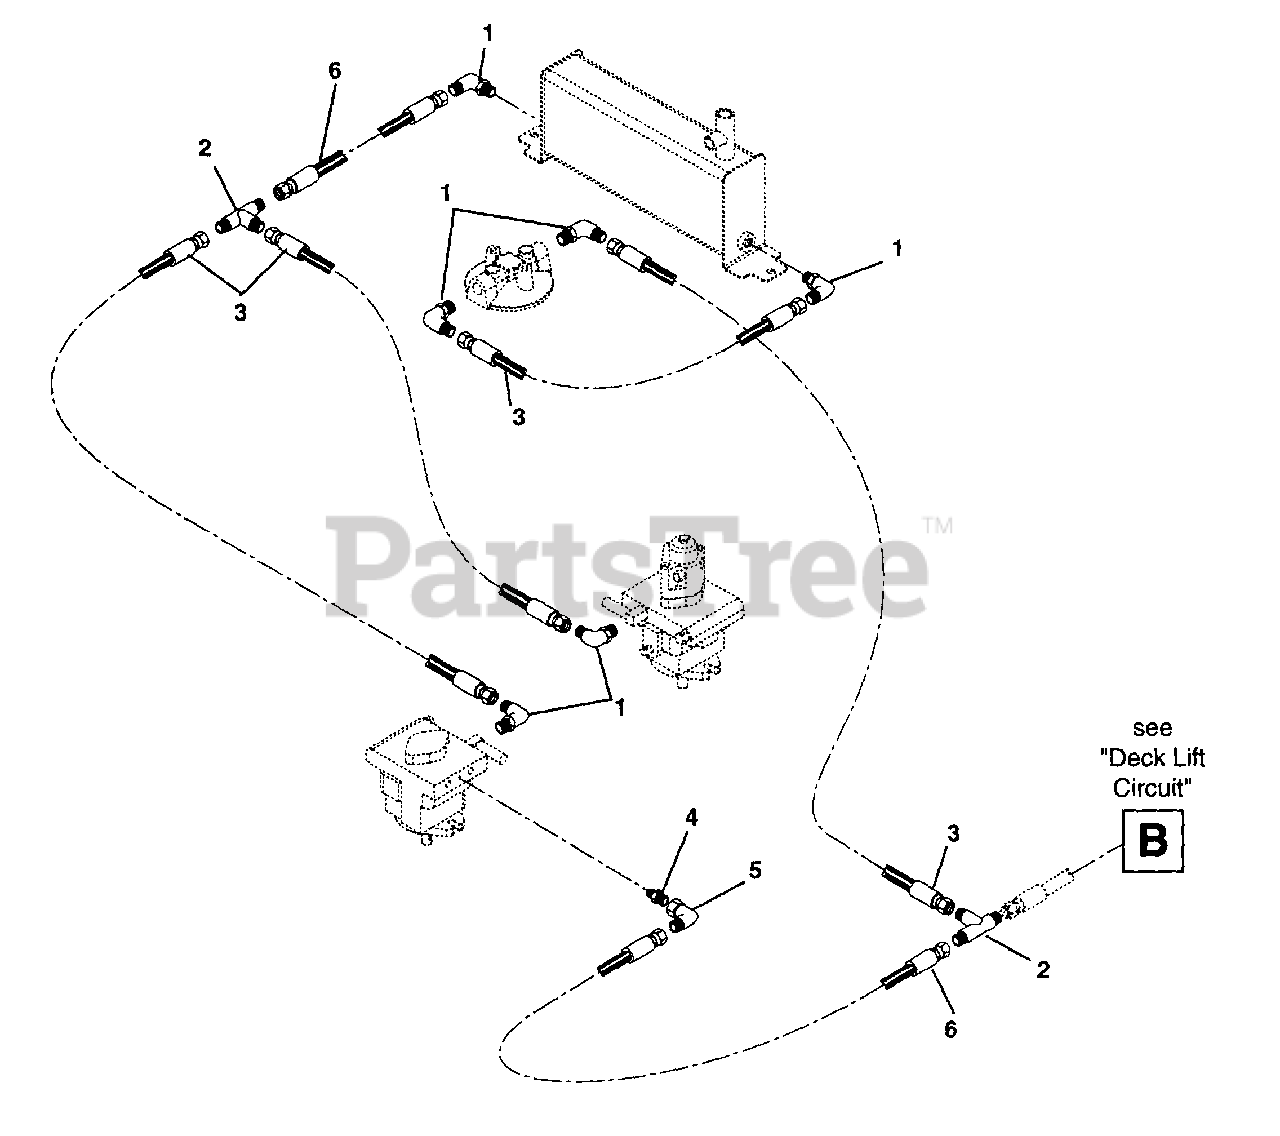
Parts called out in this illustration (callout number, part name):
1	ADPT 2503-6-6
2	ADPT-TEE .56-18
3	HOSE,HYD VALVE TO TANK
4	ADP 0503-4-6
5	ADPT 3903-6-6
6	HOSE,PUMP TO TEE
